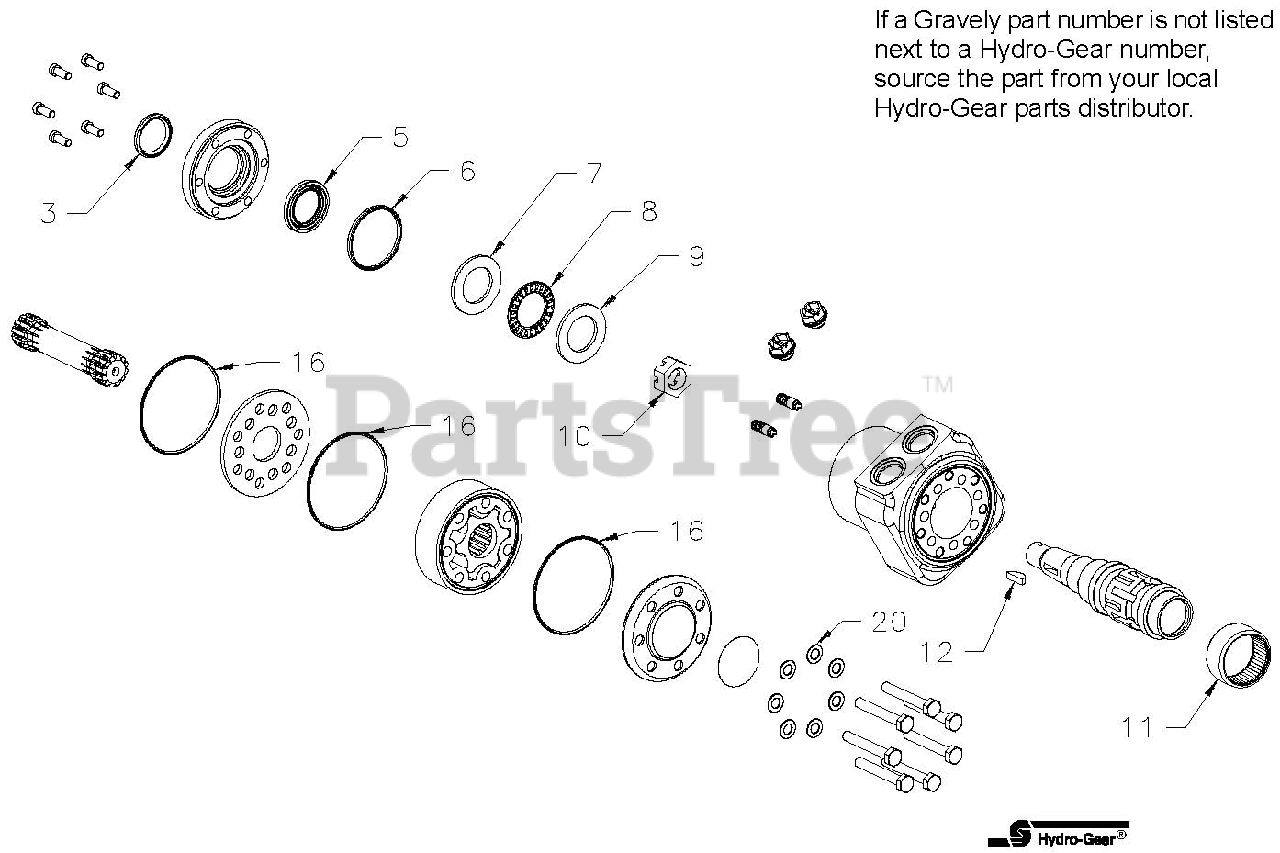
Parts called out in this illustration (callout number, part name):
10	Nut, Castle .75-20 Slotted Hex
12	Key, Woodruff .1875 x .75
NS	Seal Kit (Serial No. 5146M10001 and below)
NS	Seal Kit (Serial No. 5146M10001 and up)
NS	Kit, Axial Needle Bearing HGM P-Series
